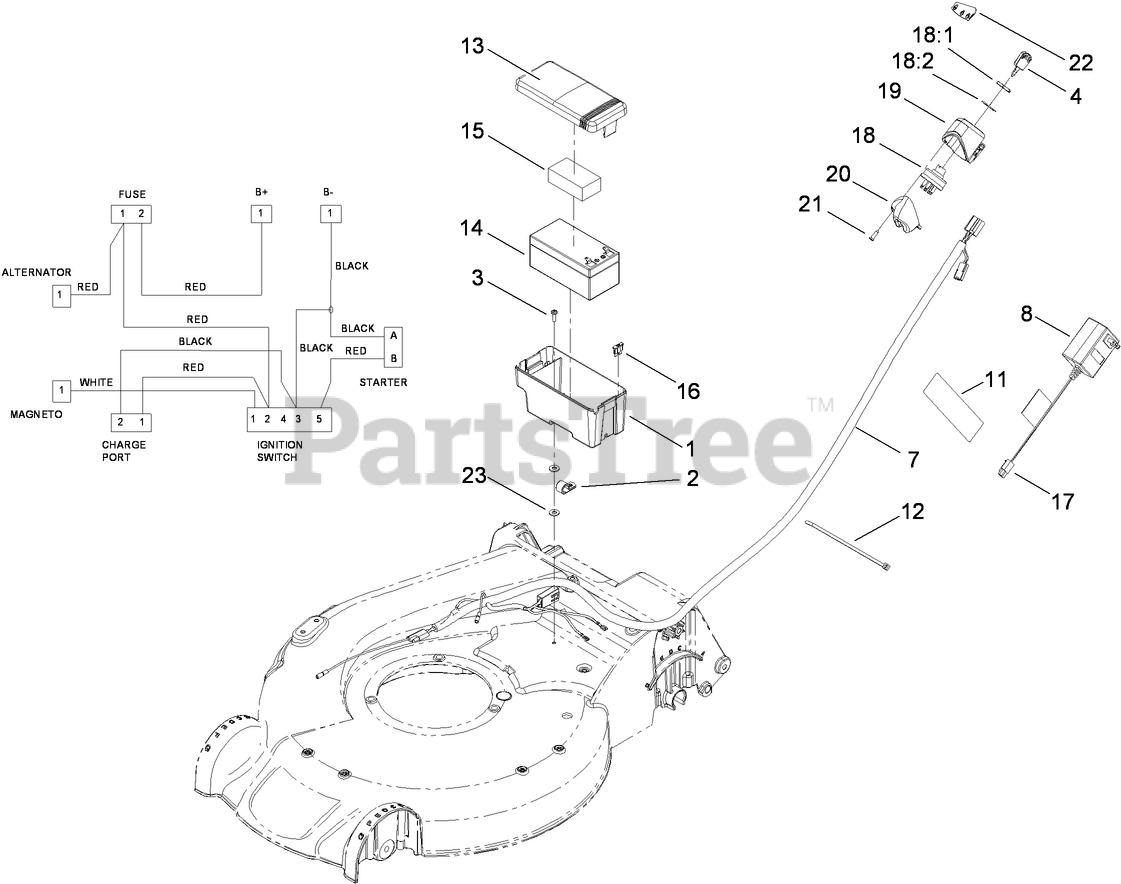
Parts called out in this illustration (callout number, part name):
1	BATTERY BOX ASM
2	CLAMP-R
7	HARNESS-WIRE
8	CHARGER-EUROPEAN, 12V DC
11	DECAL-WARNING
12	TIE-CABLE
13	DECAL-INSTRUCTIONAL
14	BATTERY-WET
15	FOAM-BATTERY, TOP
16	FUSE-40 AMP
17	ADAPTER-CHARGER
18	SWITCH-STARTER
18:1	NUT-HH
18:2	WASHER-LOCK
19	HOUSING-SWITCH, KEY
20	COVER-SWTCH
21	SCREW-PPH
22	DECAL-SWITCH, IGNITION
23	WASHER-FLAT
